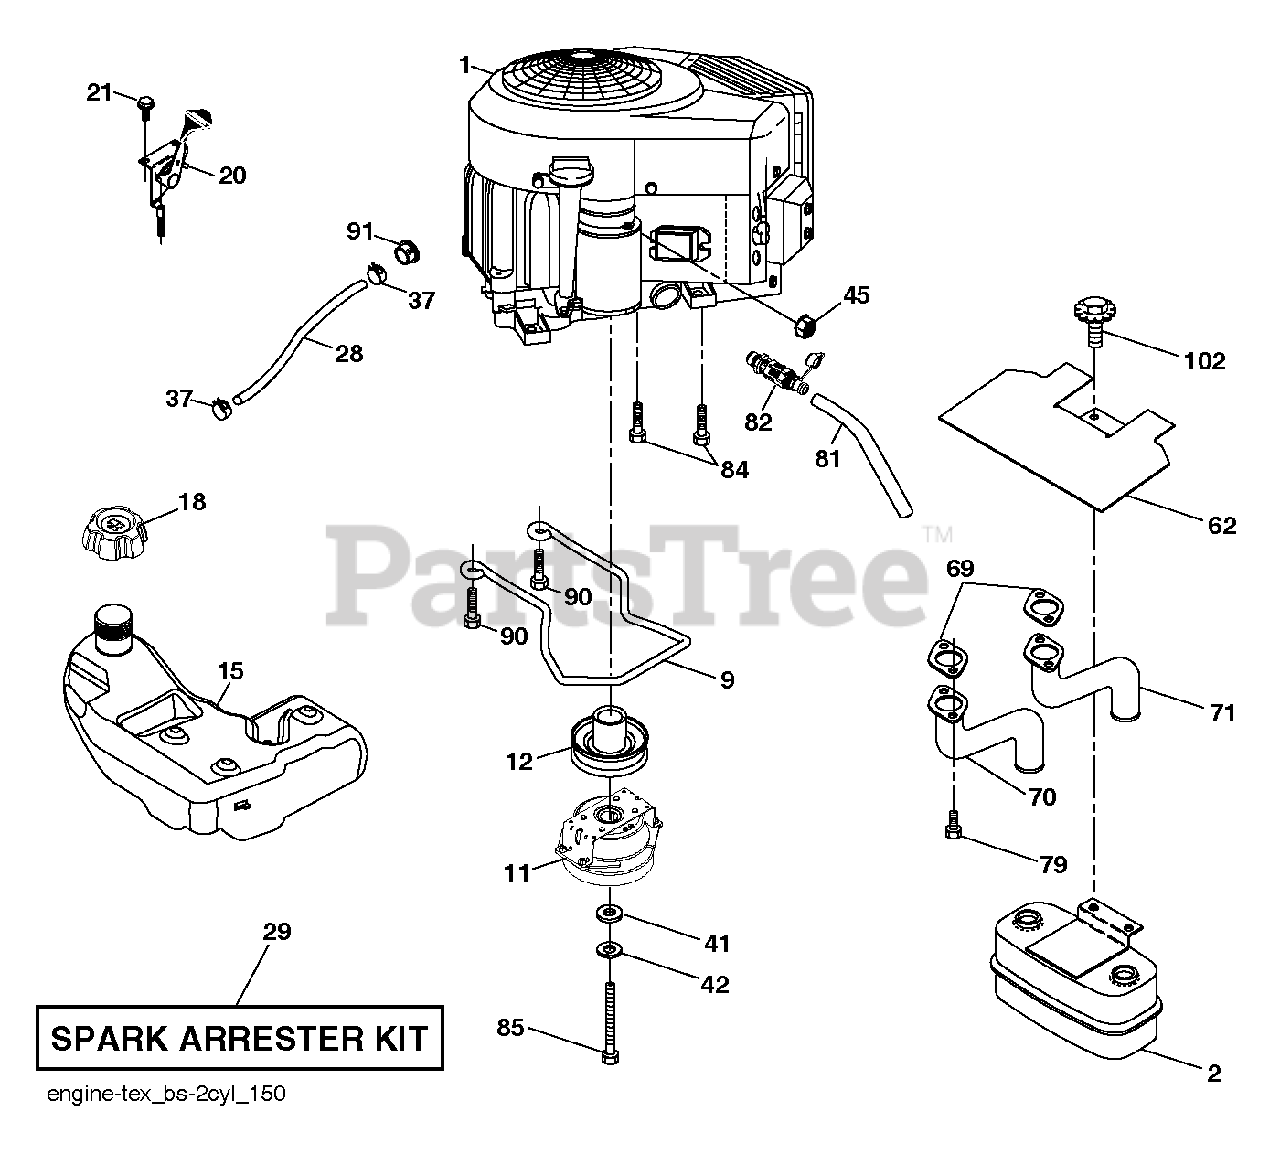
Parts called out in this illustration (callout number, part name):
2	MUFFLER.ASM.TWN.EXTNDED.DFLCTR
9	KEEPER.BELT.ENG.4.25"2.BLT.431
11	Clutch, Ogura 5.0Pd Gt1.5A-Eh07
12	PULLEY.ENGINE.TUFFTORQ
15	TANK.ASSY.3.GAL.EPA
18	Fuel Cap Assembly, 3" Black
21	SCREW.#10 X 0.750.BOS (2 2)
28	LINE.FUEL.64"REAR.EMIS
29	KIT.SPARK ARRESTOR(392390 B&S)
37	HOSE CLAMP
42	LOCKWASHER
45	NUT
62	SHIELD.HEAT.MUFFLER
69	GASKET.MUFFLER
70	EXHAUST.TUBE.LH.BS/TWIN
71	EXHAUST.TUBE.RH.B&S.TWIN.INTEK
79	SCREW.SOCKET.HEAD.5/16-18
81	TUBE, DRAIN OIL ASM.
82	VALUE.OIL.DRAIN
84	SCREW.3/8-16
85	Hex Bolt, 7/16-20 X 3.75 Gr5 Red
90	SCREW 3/8-16X1
91	BUSHING.1.375OD
102	SCREW
